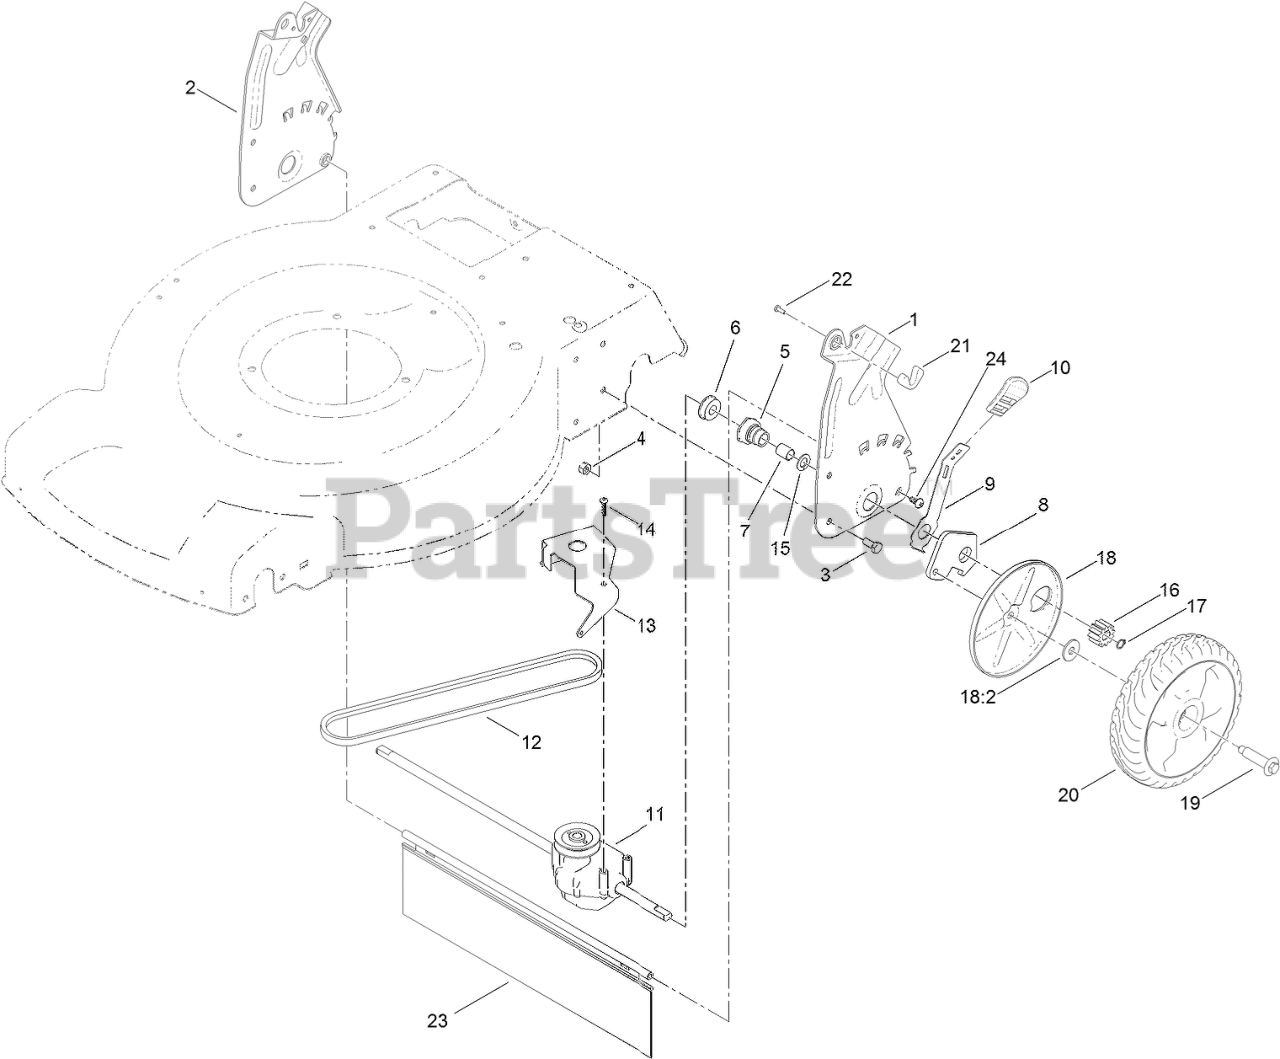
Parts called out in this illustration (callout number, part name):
1	PLATE-REAR, LH (HOC)
2	PLATE-REAR, RH (HOC)
3	SCREW-HH
4	NUT-LOCK, NI
5	RETAINER-BUSHING, HOC
6	BEARING-BALL
7	BUSHING-SLEEVE
8	ARM-PIVOT, REAR
9	ARM-SPRING
10	KNOB-HOC
11	TRANSMISSION
12	BELT-V
13	BRACKET-TRANSMISSION
14	SCREW-PLASTITE
15	WASHER-THRUST
16	GEAR-PINION
17	RING-RETAINING
18	WHEEL COVER ASM
18:2	WASHER-STEPPED
19	BOLT-SHOULDER
20	8 INCH WHEEL GEAR ASM
21	ANCHOR-BAG
22	Screw-PPH
23	SHIELD-TRAILING
24	SCREW-PTH
